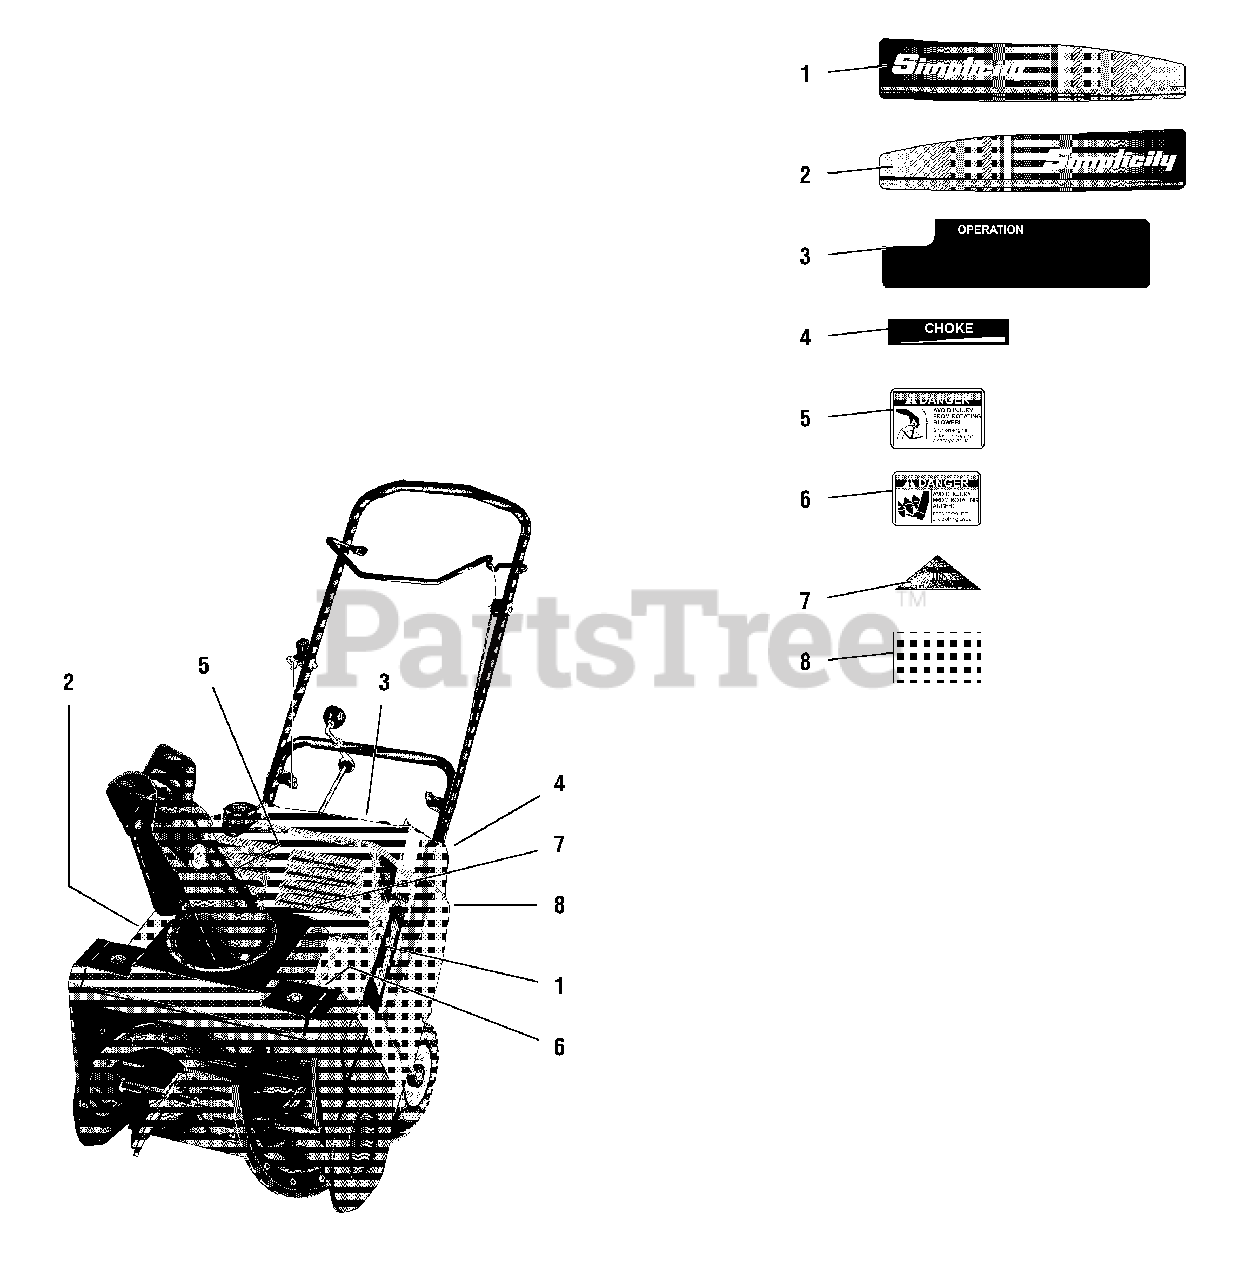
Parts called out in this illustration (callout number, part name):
1	DECAL, 551, Left Hand Side
2	DECAL, 551, Right Hand Side
3	DECAL, Console - 551M & 551E
4	DECAL, Choke
5	DECAL, DANGER, Discharge Chute
6	DECAL, Danger, Auger
7	DECAL, OPEI
8	DECAL, Mfg. No. / Ser. No.
